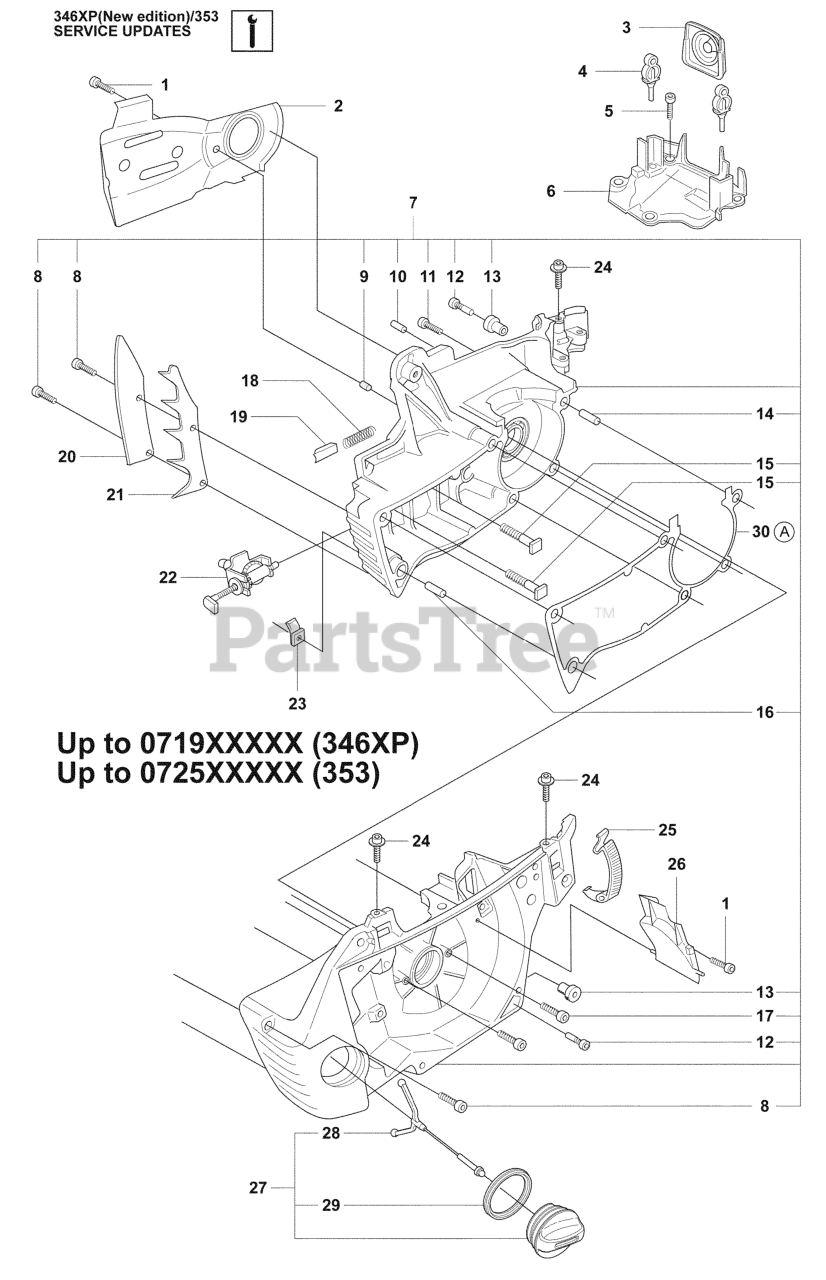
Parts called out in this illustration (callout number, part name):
4	SUPPORT
7	CRANKCASE ASSY.
13	MOVEMENT LIMITER
18	LOCK SPRING
22	CHAIN TENSIONER
23	CHAIN CATCHER
25	BUCKLE ORANGE
27	OIL TANK CAP GREY
29	OILCAP GASKET
30	GASKET SET
